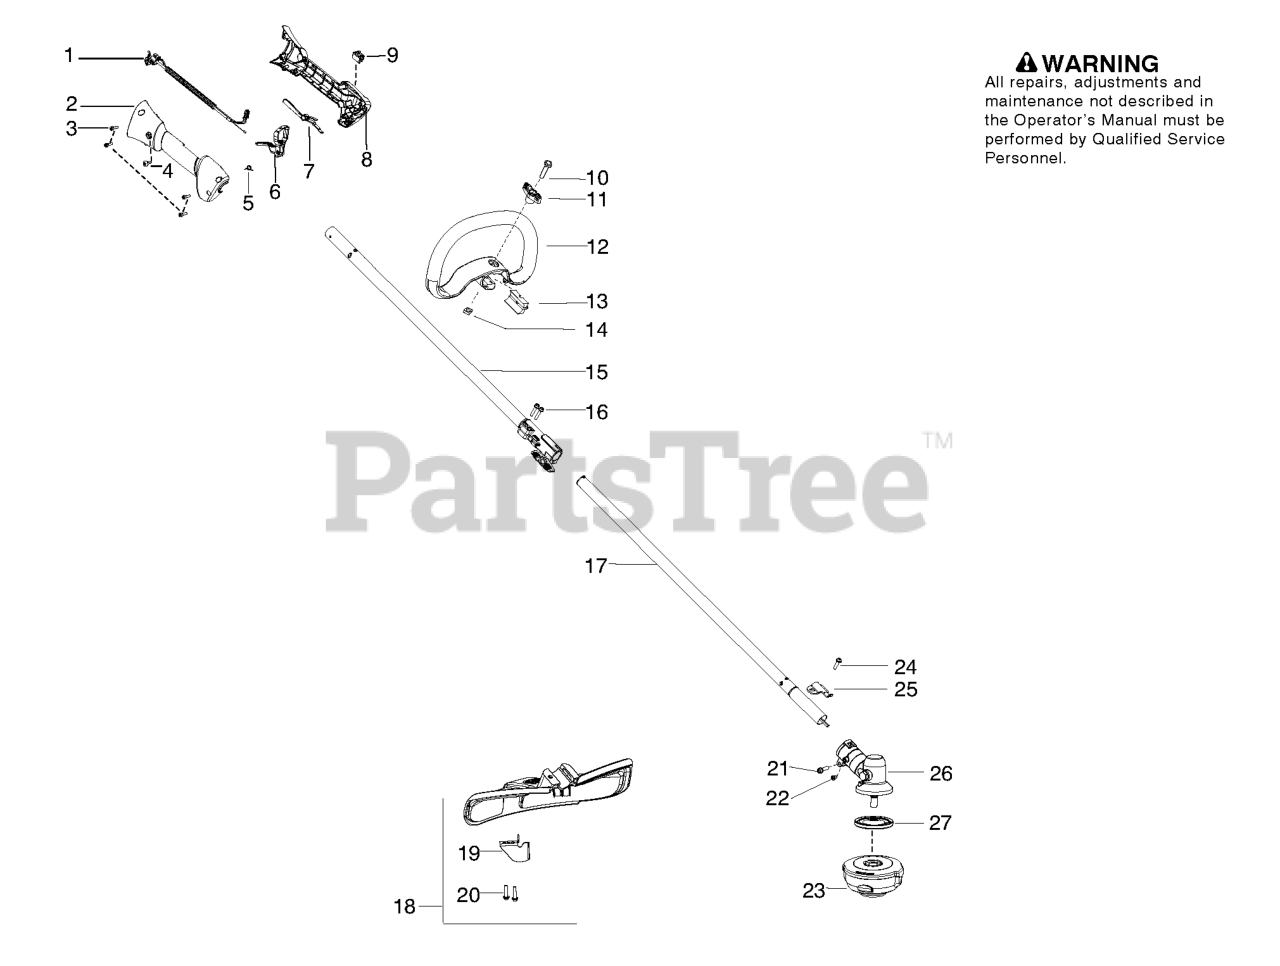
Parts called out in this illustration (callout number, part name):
1	Assy-Cable/Wire Harness
2	Housing-Throttle (RH)
3	Screw
4	Screw
5	SPRING TRIGGER
6	Trigger
7	Lockout-Throttle
8	Housing-Throttle (LH)
9	Kit-Switch
10	SCREW M6X55
12	ASSY LOOP HANDLE
13	SPACER PLASTIC
15	DRIVESHAFT
17	KIT LOWER SHAFT
18	KIT COBI SHIELD
19	Limiter-Line
21	SCREW - CARB. ADAPTOR
23	T25 TRIM HEAD 10MM LH
24	SCREW 1/4-20 X 7/8 (TAP
25	BRACKET SHIELD STRAIGHT SHAFT
26	ASSY GEARBOX
27	DRIVE DISC
